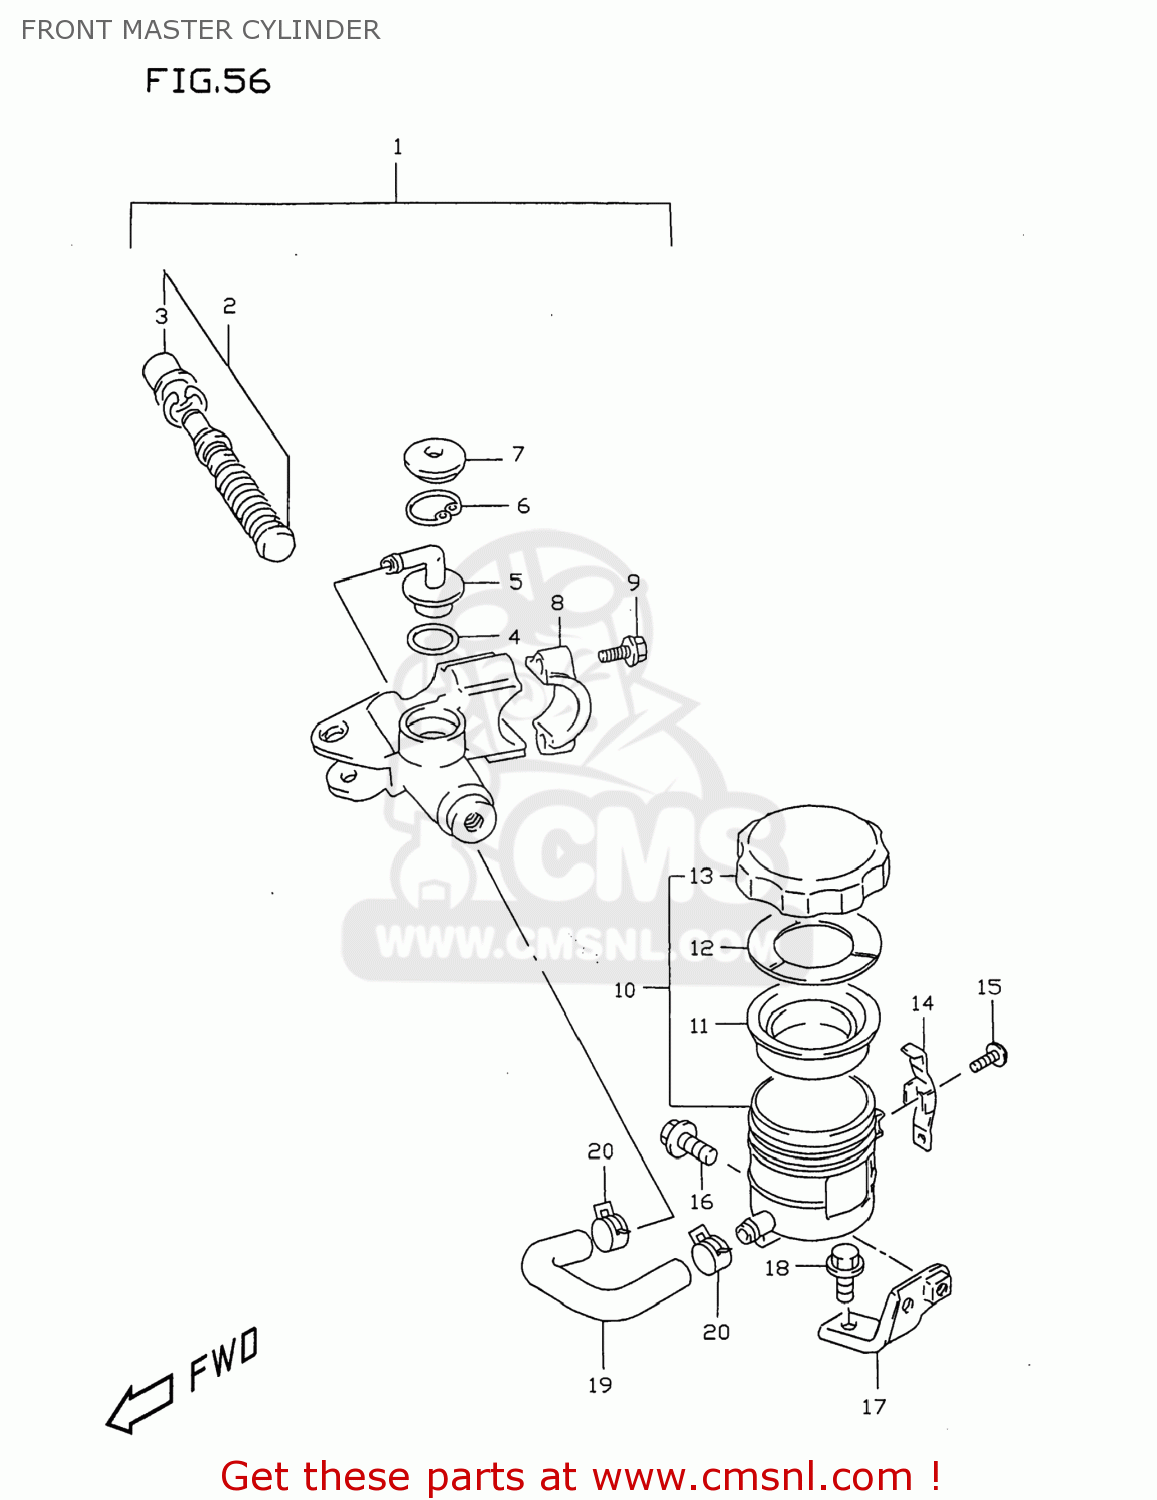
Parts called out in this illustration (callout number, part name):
1	CYLINDER ASSY,FR MASTER
2	PISTON & CUP SET
3	BOOT
4	O RING
5	CONNECTOR
6	CIRCLIP
7	COVER,DUST
8	HOLDER
9	BOLT(6X25)
10	TANK ASSY,RESERVOIR
11	DIAPHRAGM
12	PLATE,DIAPHRAGM
13	CAP
14	PLATE,RESERVOIR TANK CAP
15	SCREW
16	BOLT
17	BRACKET,RESERVOIR TANK
18	BOLT
19	HOSE,RESERVOIR TANK FR
20	CLAMP,RESERVOIR TANK FR
